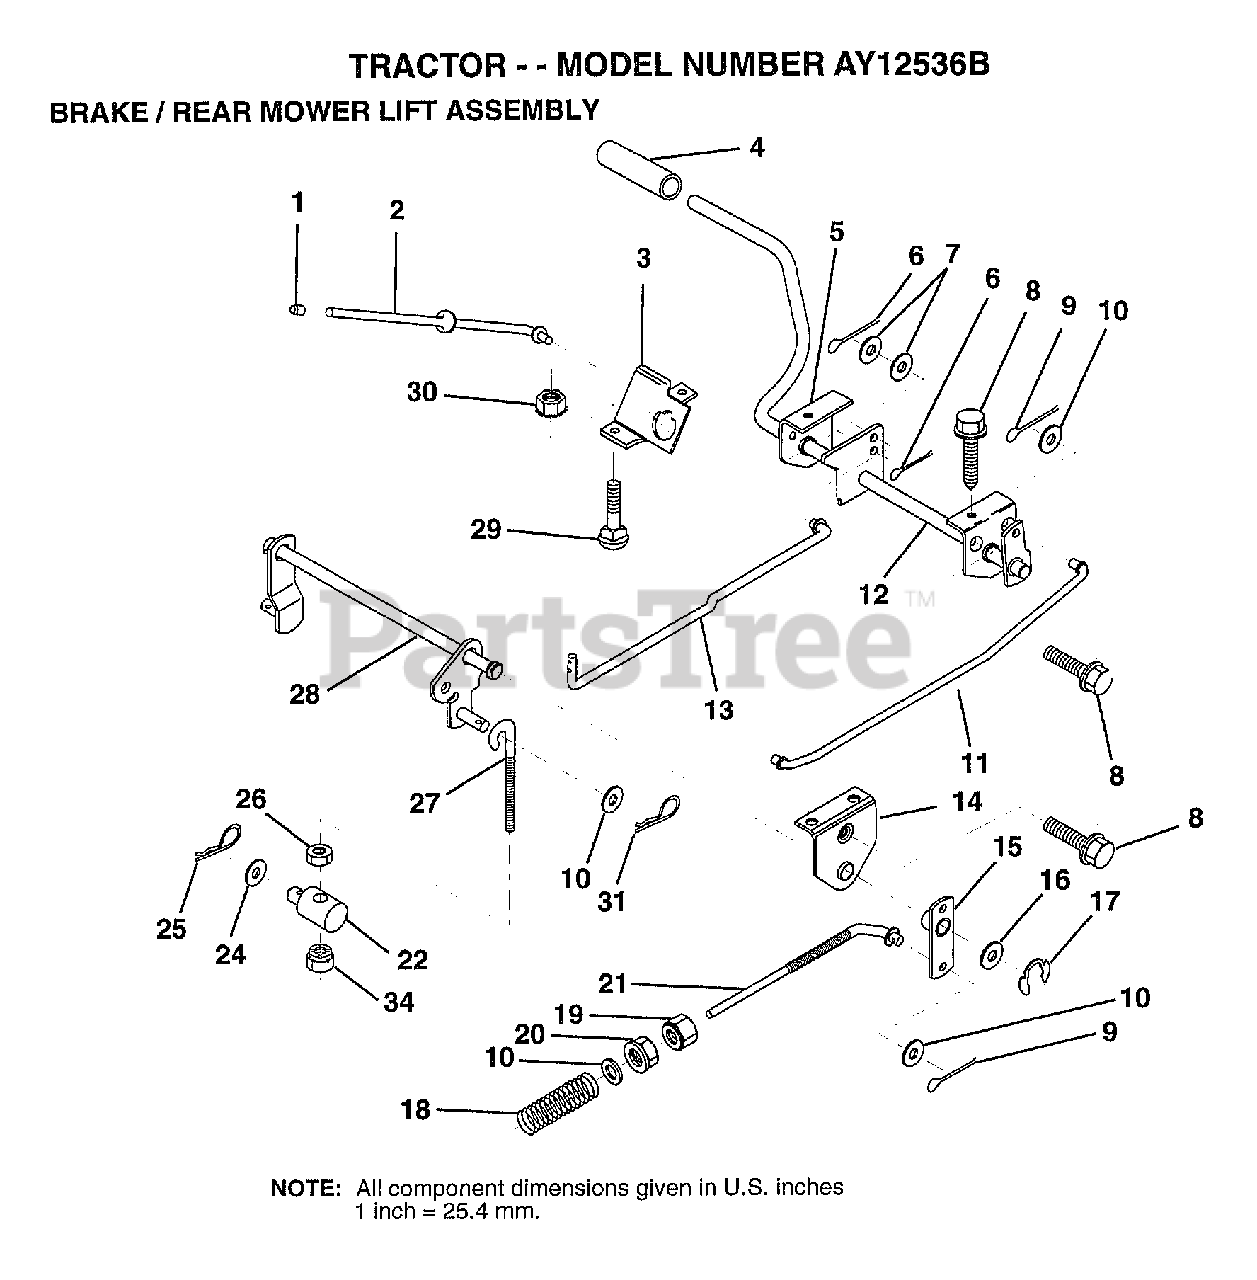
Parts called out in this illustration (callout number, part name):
1	PLUNGER CAP T
2	"ROD,PARK BRAKE"
3	"BRKT,PARK BRAKE"
4	FOOT PEDAL COVER
5	"BRKT,CLU PEDAL LH"
7	WASHER
8	SCREW LT
9	COTTER PIN
10	WASHER
11	"ROD,FRT BRAKE"
12	PEDAL ASM CL/BK36
13	"ROD,CLUTCH"
14	"BRKT,LIFT SHAFT"
15	PVT BRAKE ARM ASM
16	WASHER T
17	KLIP RING
18	SPRING ROD BRAKE
19	NUT
20	NUT
22	TRUNNION.LIFT.
24	WASHER
25	SPRING.RETAINER
26	LOCKNUT
27	"LINK, MOWER REAR"
28	LIFT ASM MOW REAR
31	RETAINER.SPRING
